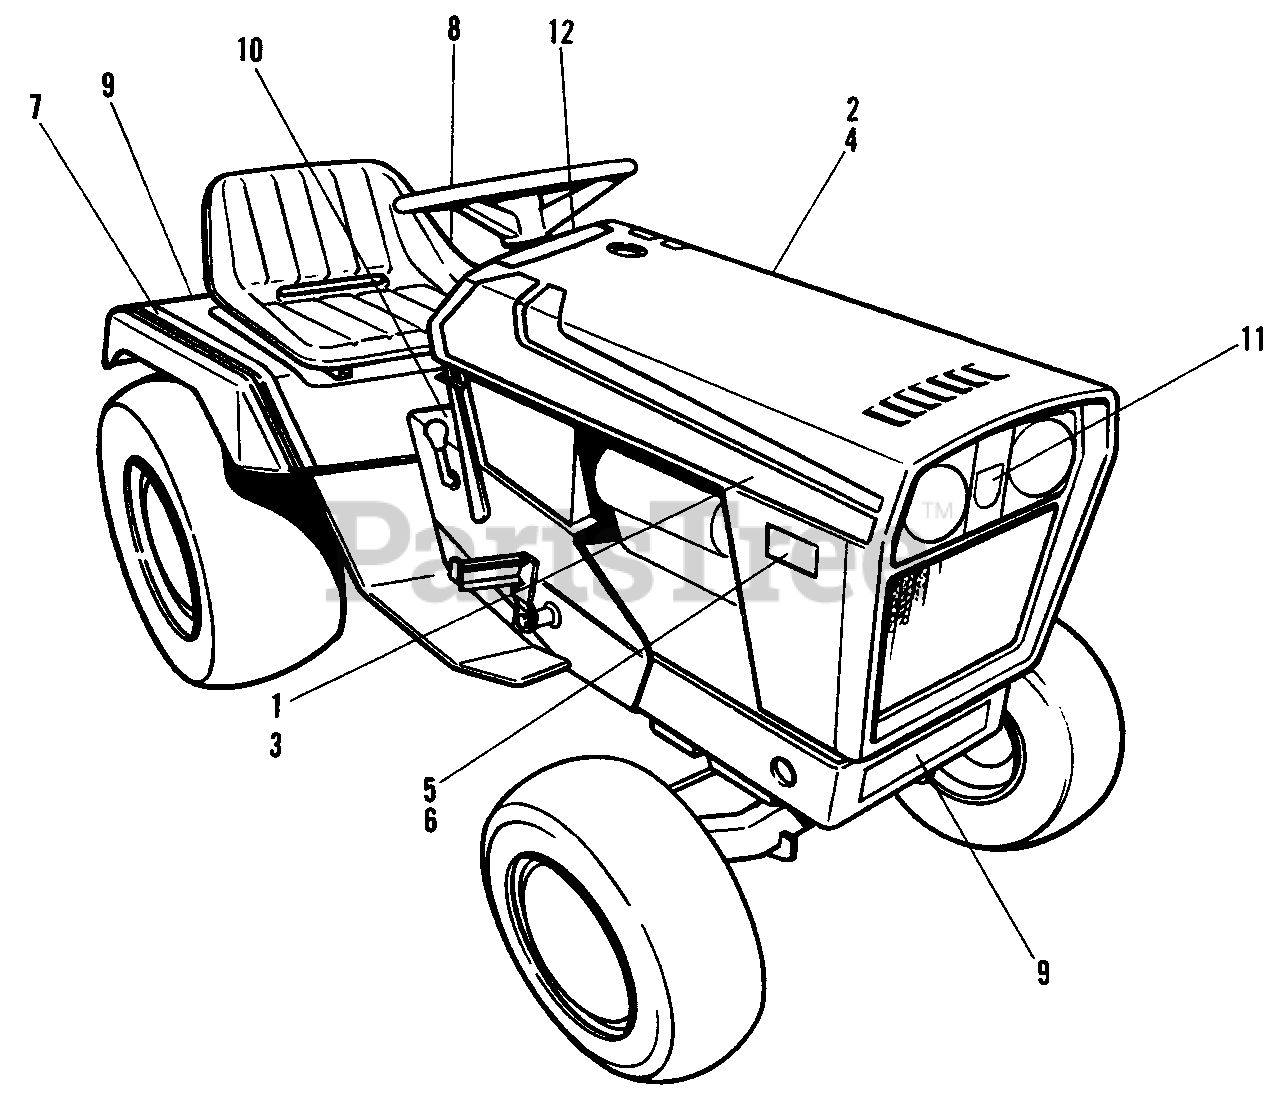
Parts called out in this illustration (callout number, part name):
1	DECAL, Hood, Landlord, R.H. (7110 Only)
2	DECAL, Hood, Landlord, L.H. (7110 Only)
3	DECAL, Hood, Sovereign, R.H. (7116 Only)
4	DECAL, Hood, Sovereign, L.H. (7116 Only)
5	DECAL, 7110 Six Speed
6	DECAL, 7116 Six Speed
7	DECAL, Seat Deck, R.H.
8	DECAL, Seat Deck, L.H.
9	DECAL, Simplicity
10	DECAL, Console, Six Speed
11	DECAL, Simplicity Grille
12	DECAL, Dash, Six Speed
12	DECAL, Caution (On Top of Engine)
12	DECAL, Drive Belts (Inside Hood)
12	DECAL, Warning (Under Seat Deck)
12	DECAL, Adjustment (Located on left side plate-red & green)
